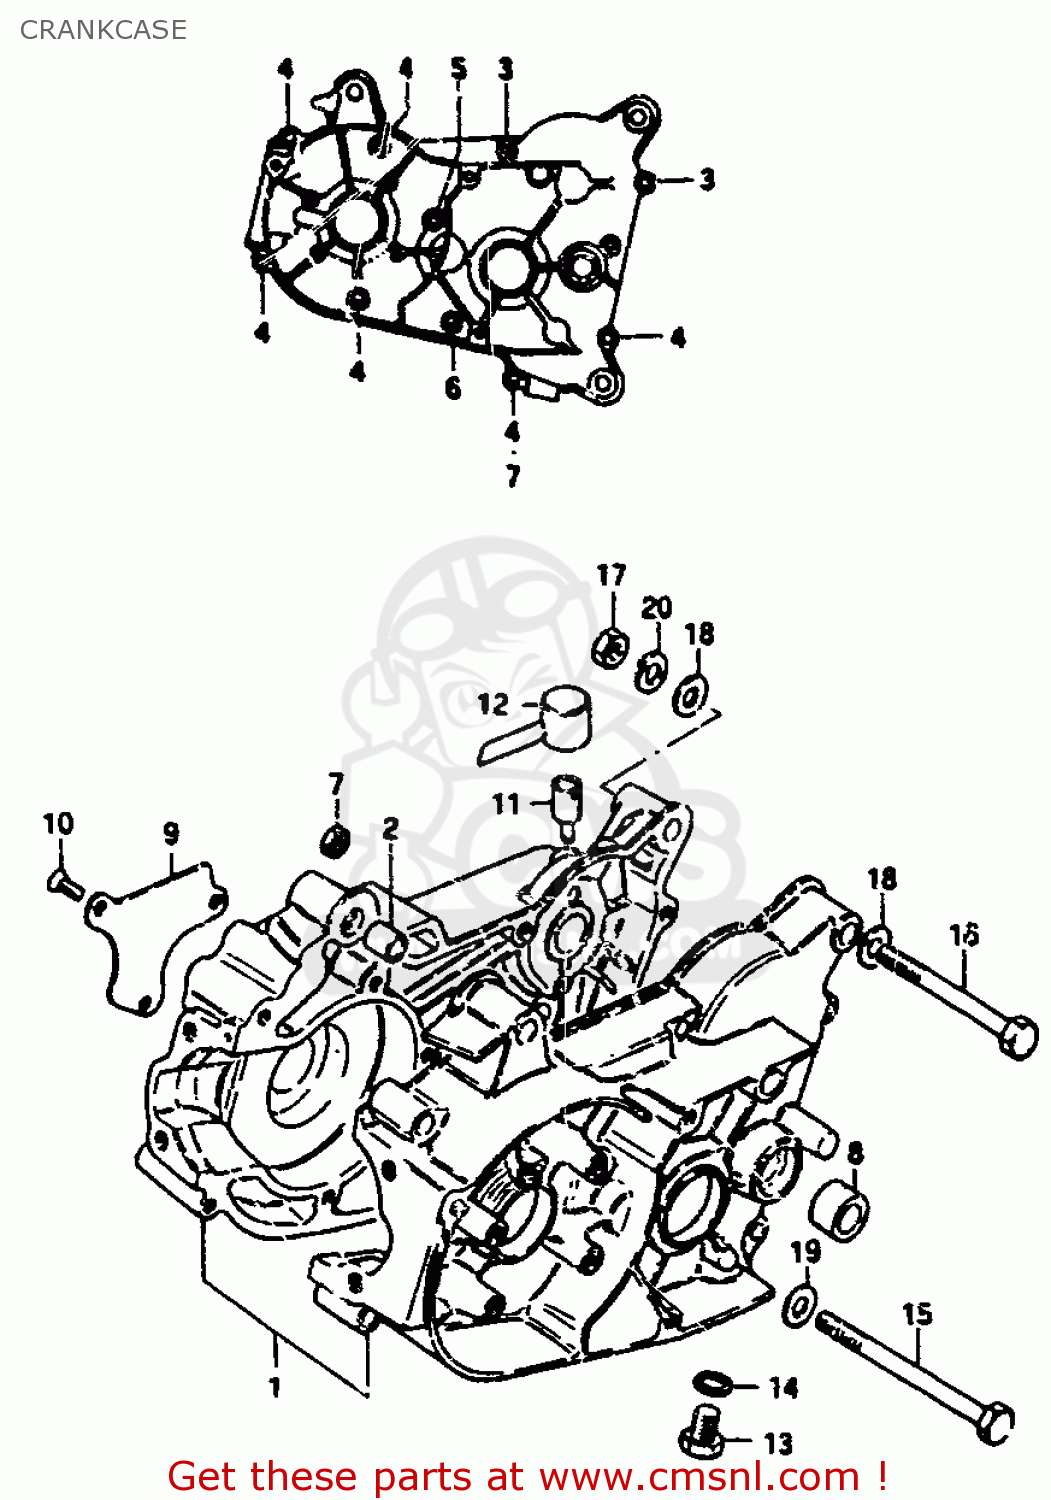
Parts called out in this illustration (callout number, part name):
1	CRANKCASE ASSEMBLY
2	PIN
3	SCREW 6X30
4	SCREW
5	SCREW
6	SCREW
7	NUT 6MM
8	BUSH
9	PLATE,OIL RESERVOIR
10	SCREW
11	PLUG,TRANSMISSION BREATHER
12	GASKET (NAS)
13	PLUG
14	GASKET(10X14X3.6) (NAS)
15	BOLT
16	BOLT
17	NUT
18	WASHER
19	WASHER
20	LOCK WASHER
